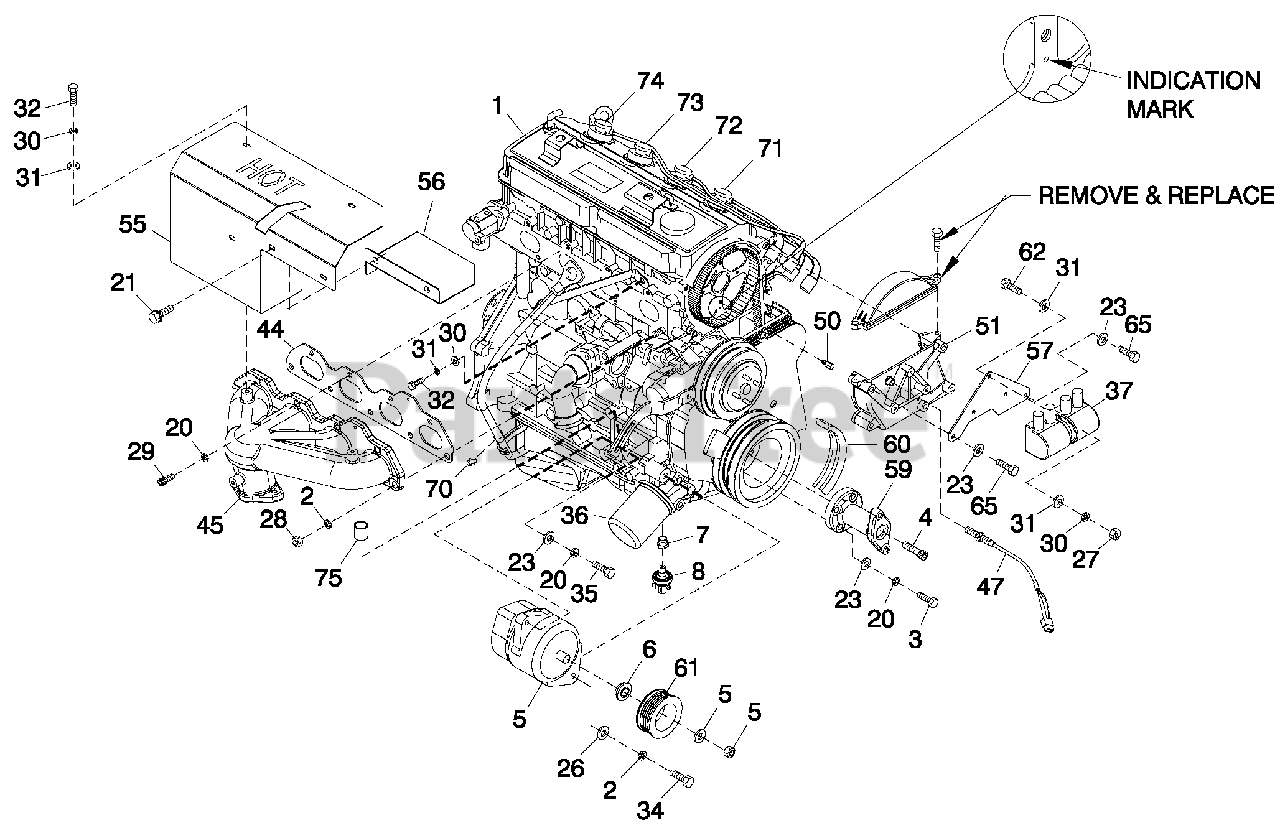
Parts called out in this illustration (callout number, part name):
1	ENGINE 2.4LG2 4G64 CERT
2	WASHER LOCK M10
3	SCREW HHC M8-1.25X 35 G8.8
4	SCREW SHC M14-1.5 X 35 G10.9
5	ALTERNATOR DC W/O UT P ULLEY
6	SPACER DC ALTERNATOR P ULLEY
7	ADAPTOR 1/8 NPTF TO 1/8 BSPT
8	SWITCH OIL PRESS URE 10 PSI 2 POL (R-PANEL)
20	WASHER LOCK M8-5/16
21	SCREW THF M6-1 X 16 N WA Z/JS
23	WASHER FLAT 5/16-M8ZINC
26	WASHER FLAT 3/8-M10ZINC
27	NUT HEX M6X1.0G8YELCHR
28	N UT HEX M10-1.25 G8YEL CHR
29	SCREW SHC M8-1.25X 25G12.9
30	WASHER LOCK M6-1/4
31	WASHER FLAT 1/4-M6 ZINC
32	SCREW HHC M6-1.0X 12 G8.8
34	SCREW HHC M10-1.5X60G8.8
35	SCREW HHC M8-1.25 X 25 G10.9
36	OIL FILTER G2 ENGINE
37	COIL PACK
44	GASKET EXHAUST MANIFOLD
45	EXHAU ST MANIFOLD G2 (MACHINE) (25KW, 35KW & 45KW)
47	ASSY MAGPICK UP(3/8-24 MALE)
50	CAM SENSOR PIN ASSY
51	COVER CAM GEAR G2 REWORKED
55	SHIELD HEAT G2
56	SHIELD HEAT SML
57	BRACKET COIL PACK
59	ADAPTER 2.4L CRANKSHAFT MACH
60	POLY V-BELT G2 (3600 RPM)
61	P ULLEY DC ALTERNATOR (3600 RPM)
62	SCREW HHC M6-1.0 X 35 G8.8 BLK
65	SCREW HHC M8-1.25X70G8.8
70	O-RING SIZE 9.0MM X 2.0MM NITR
71	CABLE, SPARK PLU G, NO.1
72	CABLE, SPARK PLU G, NO.2
73	CABLE, SPARK PLU G, NO.3
74	CABLE, SPARK PLU G, NO.4
75	PLUG TAPER
